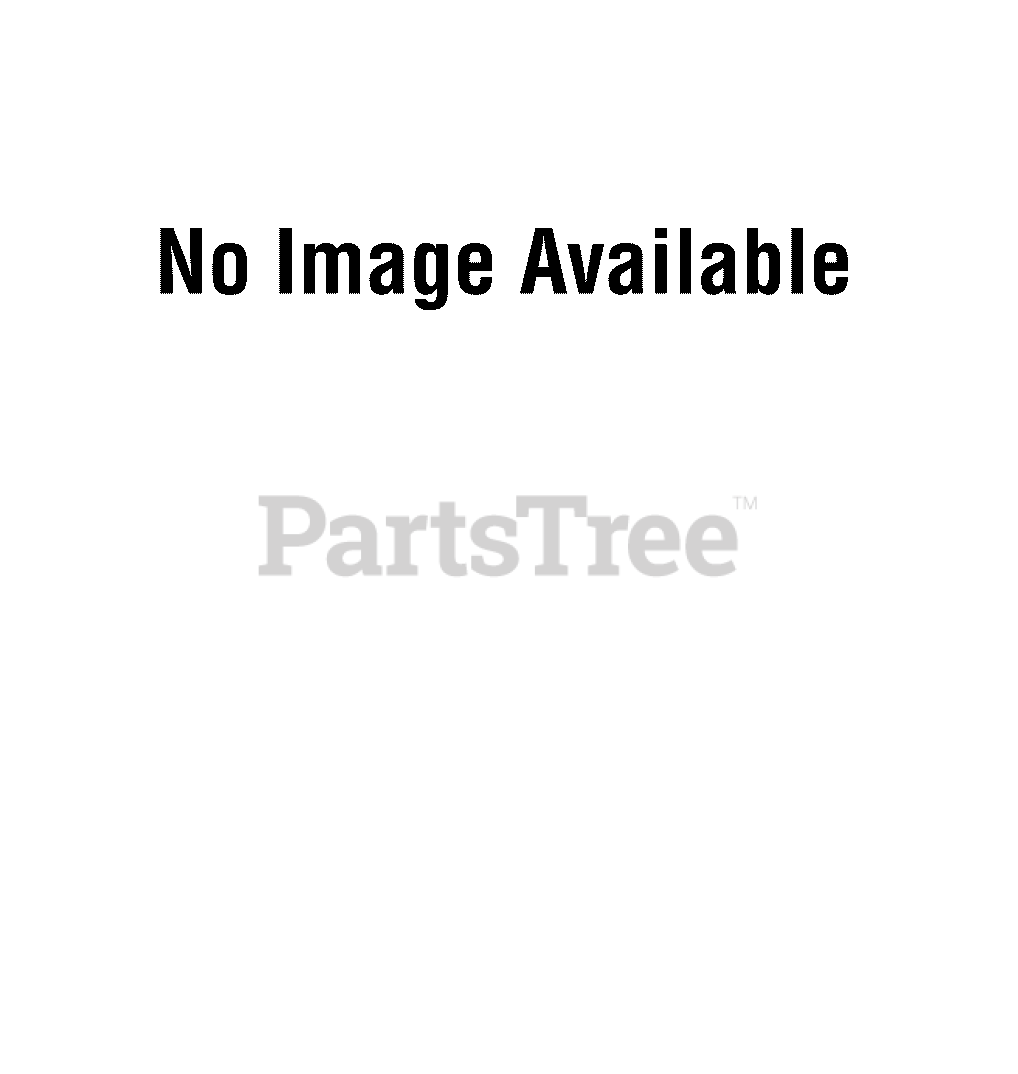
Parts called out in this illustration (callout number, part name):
1	ENGINE, SUBARU
2	PULLEY, ENGINE (VENTURE) (C0603)
3	KEY, PULLEY (VENTURE) (B0210)
4	ENGINE PULLEY SPACER (F0691)
5	WASHER, 3/8 FENDER (A0194)
6	BOLT, 3/8-24 X 3/4 (A0193)
7	BREATHER TUBING
8	OIL DRAIN
9	SQUARE HEAD SET SCREW, 5/16-18 X 1/2 (A0192)
10	BELT, V, AK36 38.00 OC OHR, KVR CD
